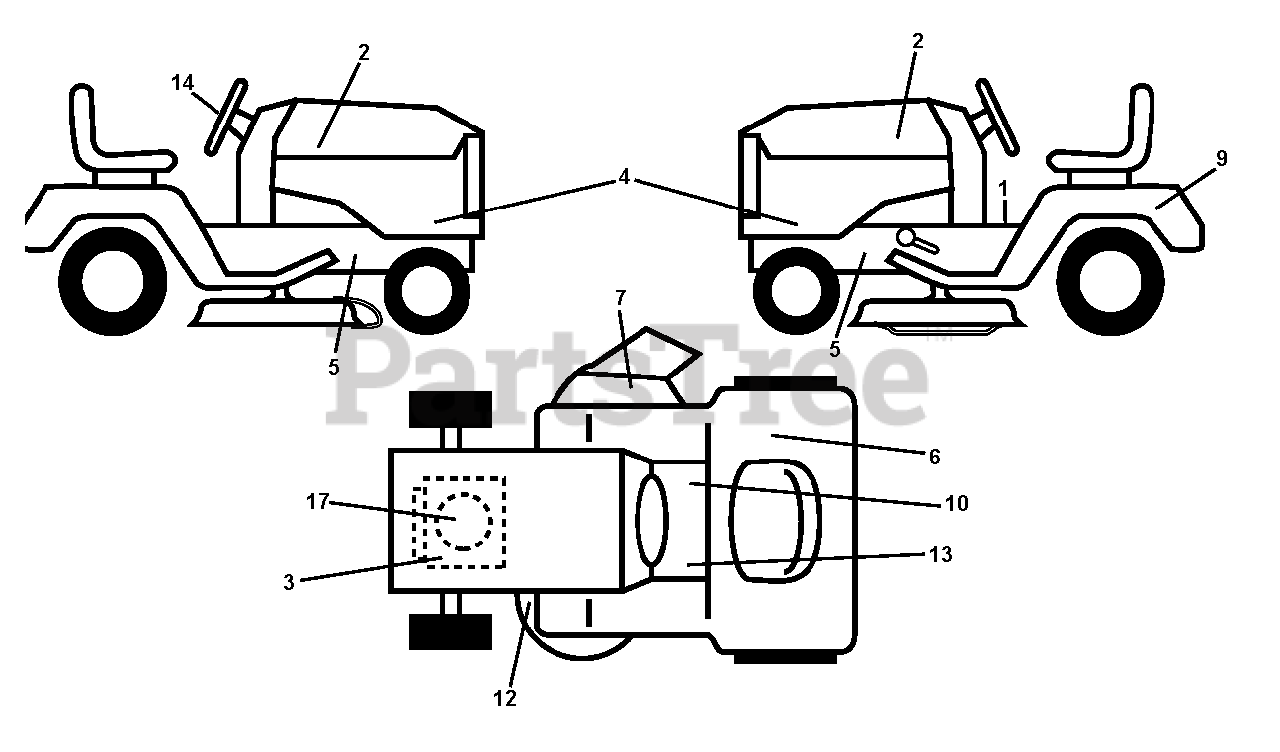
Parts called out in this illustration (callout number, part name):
6	Decal, 100 DB/CE
7	DECAL, WARN. DEFLECT/CTFGR
9	DECAL BTRY SYMBOLS
10	DECAL PARK BRAKE
